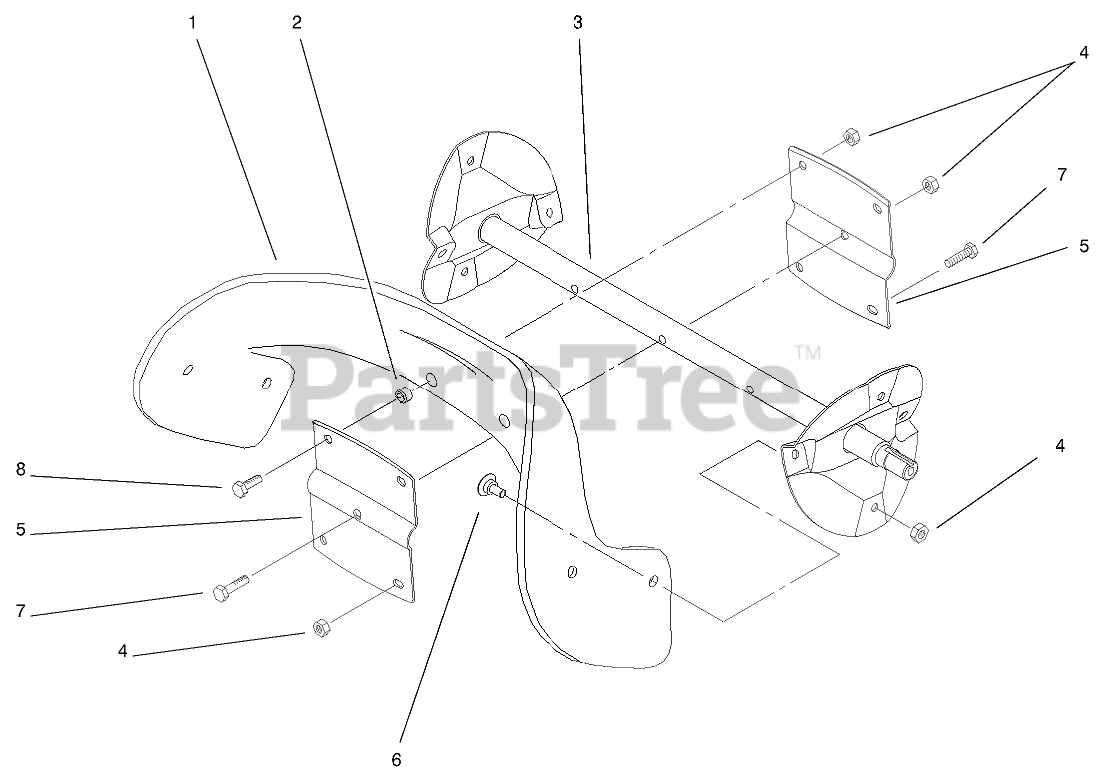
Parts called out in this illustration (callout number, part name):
1	BLADE-ROTOR
2	SPACER-BLADE, ROTOR
3	ROTOR ASM
4	NUT-LOCK, NI
5	HALF-ROTOR
6	SCREW
7	SCREW-HH
8	SCREW-HH
